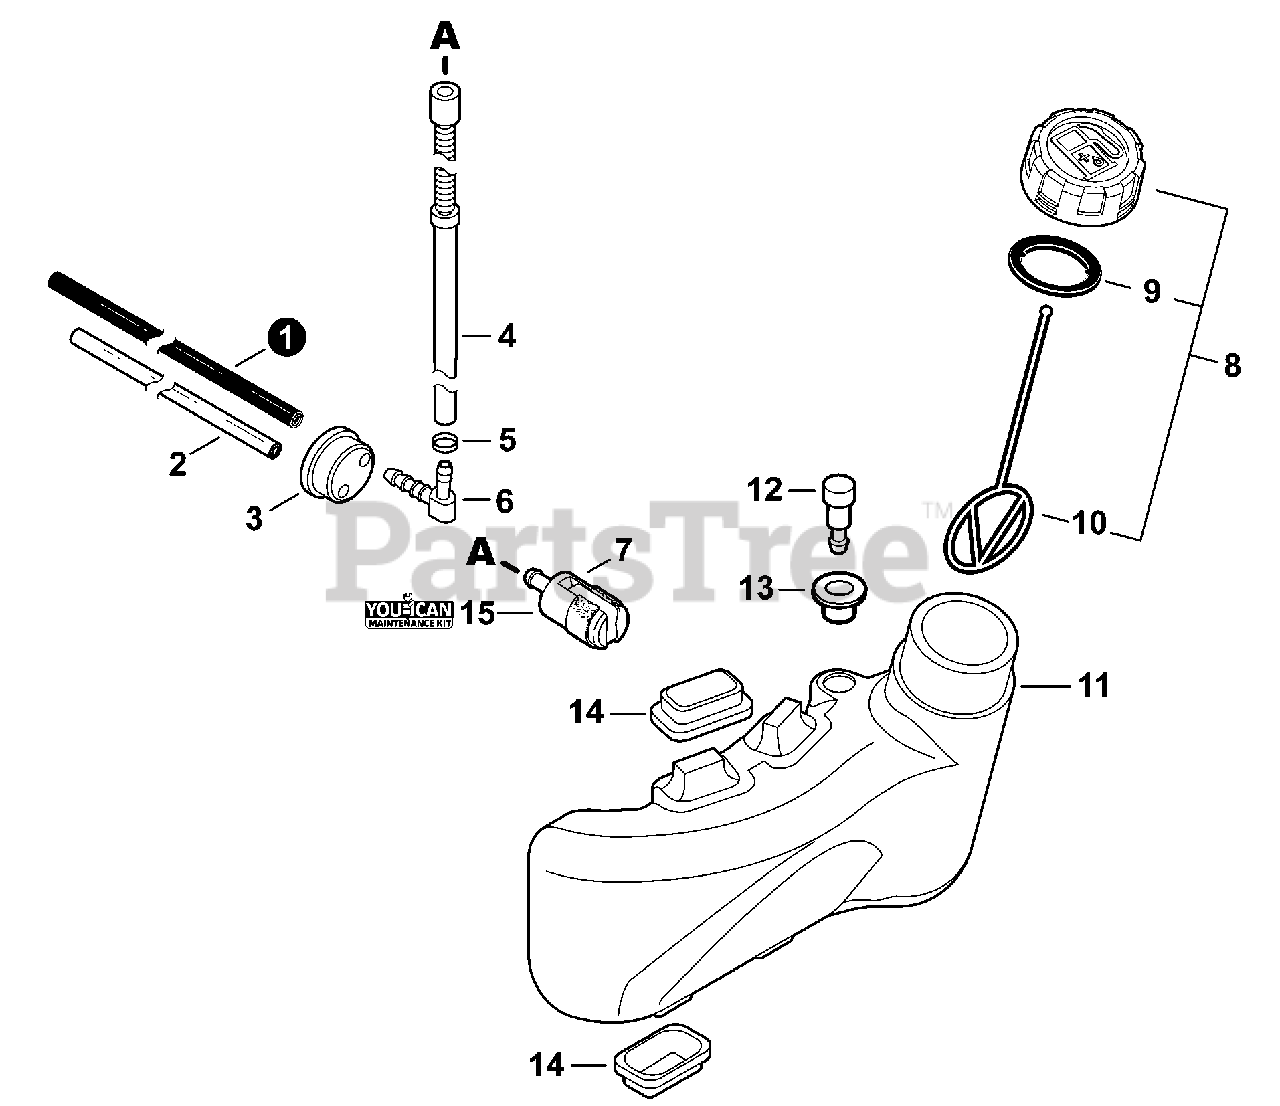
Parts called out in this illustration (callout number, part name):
1	PIPE, FUEL 3×5×83 BLACK
2	PIPE, FUEL 3×6×85 CLEAR
3	GROMMET, FUEL
4	PIPE, FUEL
5	CLIP Ø6.5MM
6	CONNECTOR, PIPE
7	FILTER, FUEL
8	CAP ASSY, FUEL
9	GASKET, FUEL CAP
10	CONNECTOR, CAP L= 123
11	TANK, FUEL
12	VENT ASSY
13	GROMMET, FUEL
14	CUSHION
15	PLUG & FILTER KIT - YOU CAN
